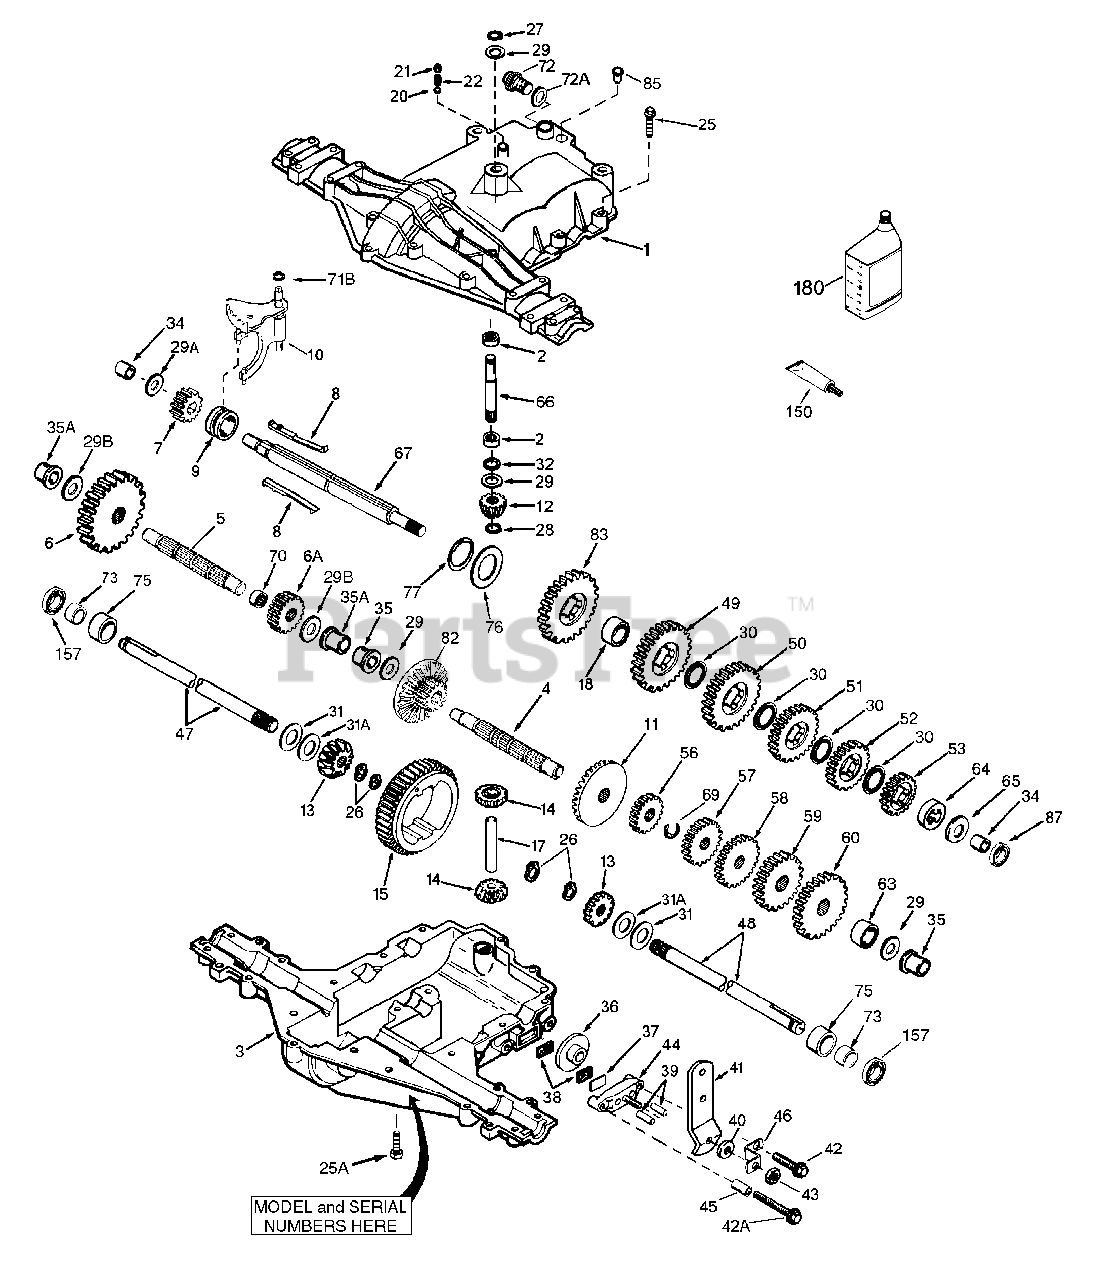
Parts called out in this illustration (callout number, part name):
1	Transaxle Cover
2	Needle Bearing 5/8" ID
3	Transaxle Case
4	Countershaft
5	Output Shaft
6	Spur Gear (38 teeth)
6A	Spur Gear (15 teeth-steel)
7	Spur Gear (11 teeth-steel)
8	Shift Key
9	Shift Collar
10	Shift Rod & Fork
11	Bevel Gear (30 teeth)
12	Input Bevel Pinion (13 teeth)
13	Bevel Gear (16 teeth-steel)
14	Bevel Gear (16 teeth-steel)
15	Ring Gear (43 teeth)
17	Drive Pin
20	Ball 5/16" dia
21	Set Screw 3/8-16 x 3/8"
25	Screw 1/4-20 x 1-1/4"
25A	Screw 1/4-20 X 1-3/8"
26	Retaining Ring
27	Retaining Ring
28	Retaining Ring
29B	Thrust Washer
31	Washer (.056 wide)
31A	Flat Washer (.062 wide)
32	Oil Seal 5/8"
35	Flanged Bushing
35A	Flanged Bushing 3/4"
36	Brake Disk
37	Brake Pad Plate
38	Brake Pad
39	Dowel Pin
41	Brake Lever
42	Screw 1/4-20 x 1-1/4"
42A	Screw 1/4-20 x 2-1/4"
43	Locknut 5/16-24
44	Brake Pad Holder
46	Brake Lever Bracket
47	Axle (12-7/32" long)
48	Axle (16-13/16" long)
49	Spur Gear (29 teeth-steel)
50	Spur Gear (23 teeth-steel)
51	Spur Gear (19 teeth-steel)
52	Spur Gear (16 teeth-steel)
53	Spur Gear (15 teeth-steel)
56	Spur Gear (11 teeth-steel)
57	Spur Gear (17 teeth-steel)
58	Spur Gear (21 teeth-steel)
59	Spur Gear (24 teeth-steel)
60	Spur Gear (25 teeth)
63	Countershaft Spacer 1-1/8" x 3/8"
64	Brake Shaft Spacer 1-3/8" X 3/8"
66	Input Shaft
67	Shifter & Brake Shaft
69	Retaining Ring
72	Threaded Plug 9/16-18
73	Needle Bearing 3/4"
75	Sleeve .999 ID
77	Inverted Retaining Ring
82	Bevel & Spur Gear (30 & 13 teeth)
83	Spur Gear (27 teeth)
85	Oil Fill Plug
87	Oil Seal 9/16"
150	Liquid Gasket RTV Silicone
157	Oil Seal 3/4"
180	Gear Oil 80W90
